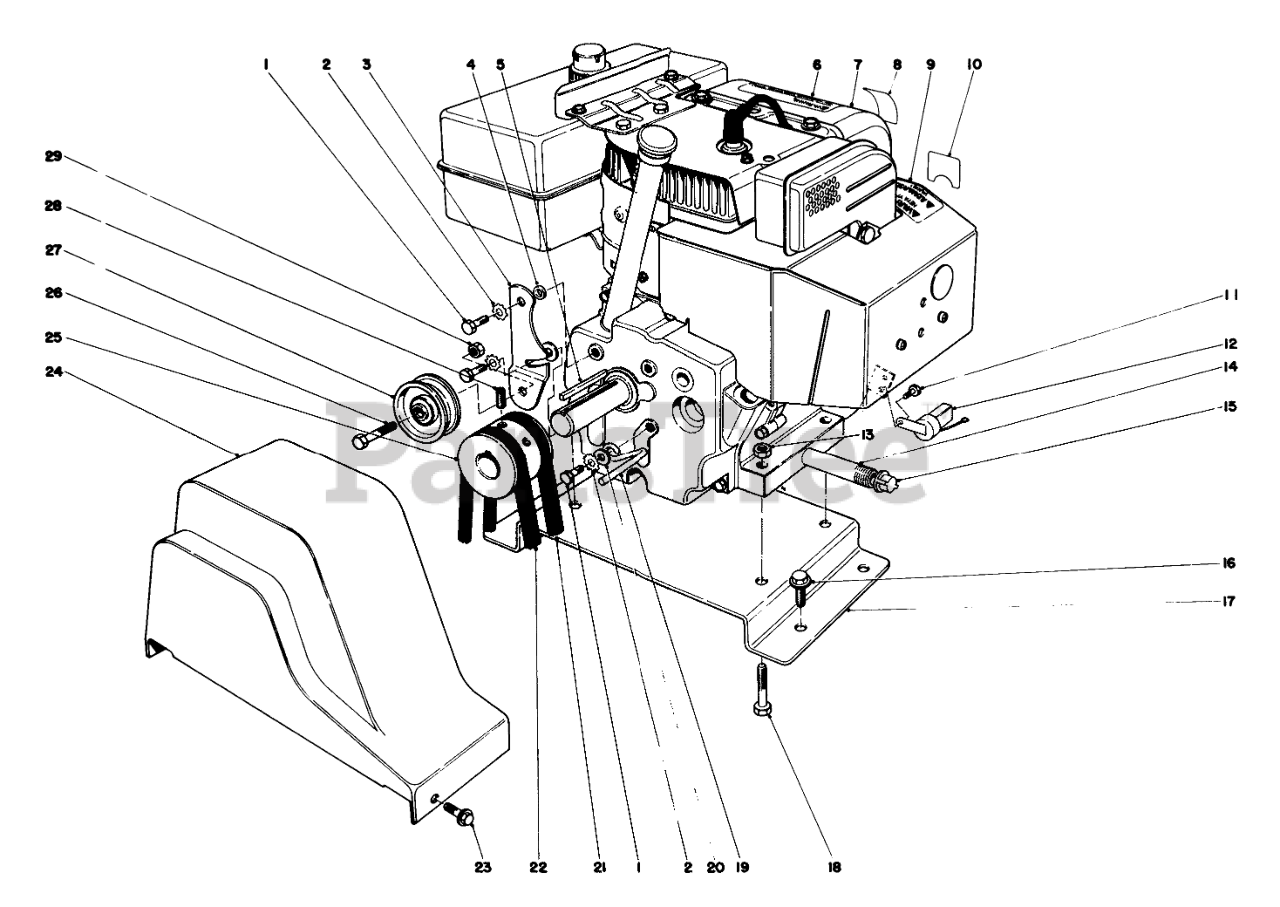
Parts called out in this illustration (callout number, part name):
1	SCREW-HH
2	WASHER-LOCK
3	ENGINE IDLER ARM
4	SPACER
6	HAZARDS CAUTION DECAL
7	Engine
8	Decal-Primer
9	Decal
10	CHOKE DECAL
11	SCREW
12	INTERLOCK MODULE
13	NUT-LOCK, NI
14	NIPPLE-PIPE
15	CAP-PIPE
16	SCREW-HHFTF
17	WHEEL ASM
18	SCREW-HH
19	BELT RETAINER
20	WASHER-PLAIN
21	V-BELT
22	V-BELT
23	SCREW-HWH
24	BELT GUARD
25	Pulley
26	SCREW-HH
27	PULLEY-IDLER
28	Screw-Set
29	NUT-HEX
